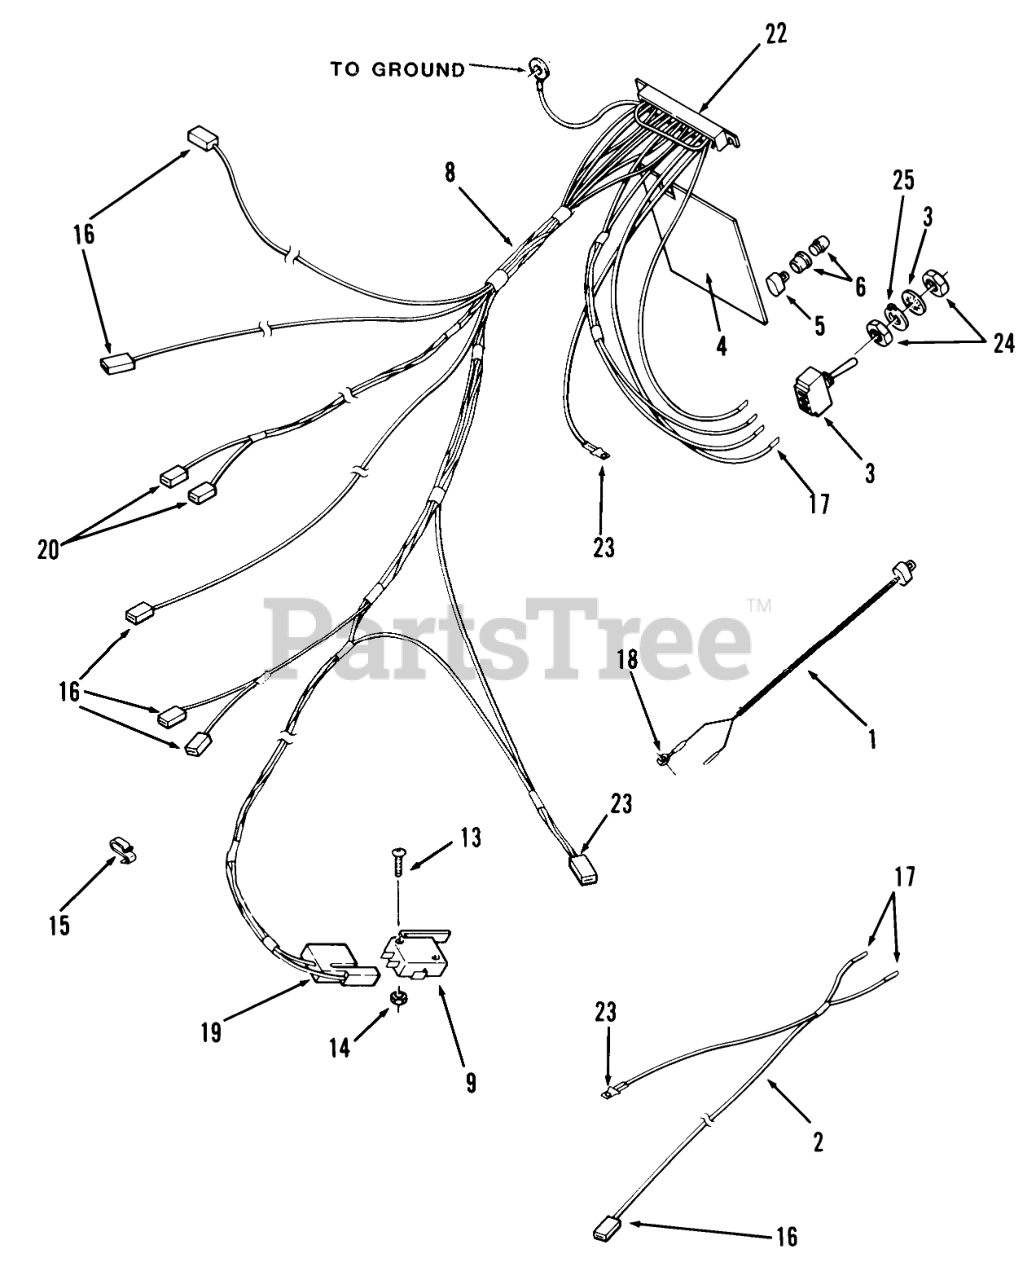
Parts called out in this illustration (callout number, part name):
1	LIGHT INDICATOR
2	ASSY WIRE INDICATOR
3	SWITCH TOGGLE
4	P.C. Board (includes item 2)
4	P.C. Board w/ lights 417-s, 420 Only
5	LIGHT INDICATOR
6	ASSY LENS & BUSHING
8	WIRING HARNESS
9	SWITCH
13	Screw
14	NUT HEX 4-40 ELAST
15	CLIP-CABLE
16	Piggy-Back Connector (Part of 6)
17	062 X 031 TAB RECEPT
18	Ring Terminal (Part of 1)
19	CONNECTOR BODY
20	Piggy-Back Connector(Part of 6)
22	Molex Connector (Part of 6)
23	Connector Part of 5
24	NUT F/W 116796
25	RING LOCKING
